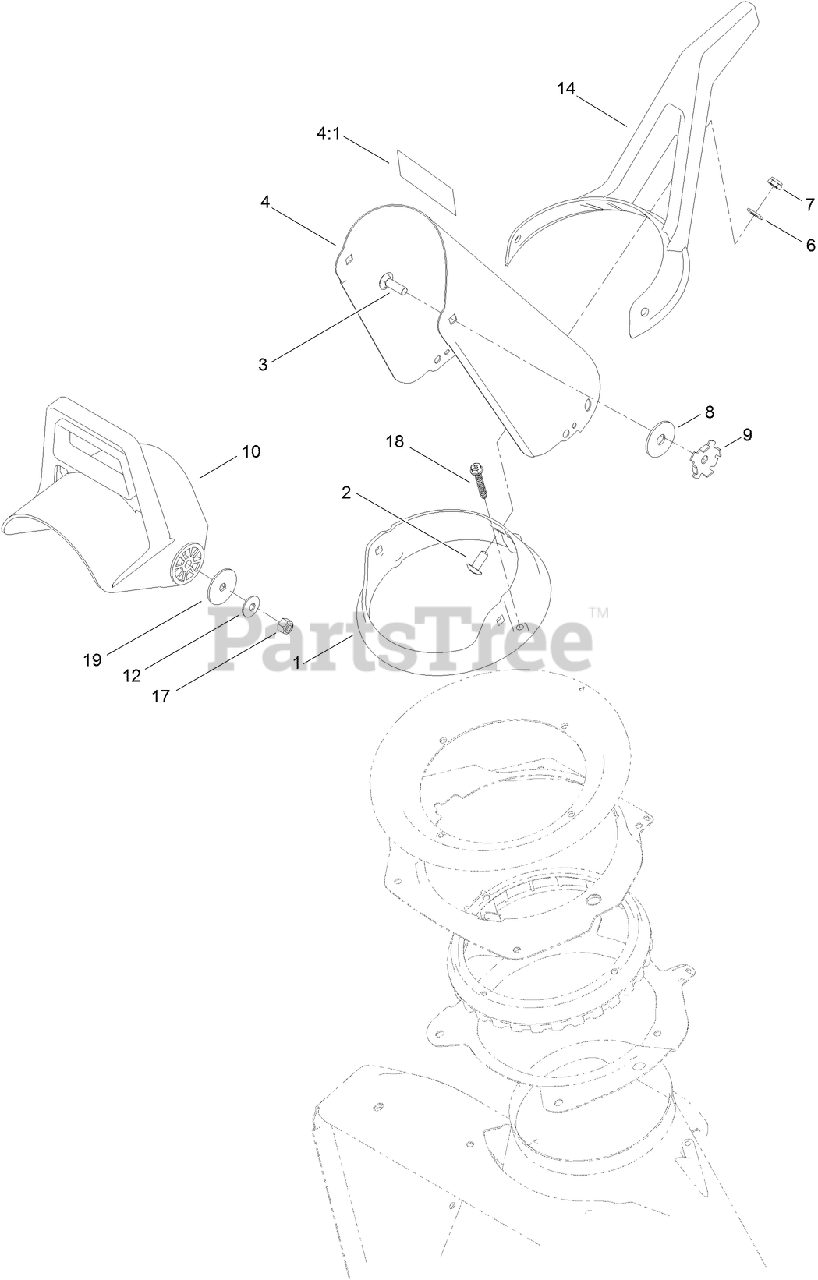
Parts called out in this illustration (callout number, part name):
1	RING-CHUTE
2	SCREW-PTH
3	SCREW-CARR
4	DISCHARGE CHUTE ASM
4:1	DECAL-DANGER, CE
6	WASHER-FLAT
7	NUT-LOCK, NI
8	WASHER-RUBBER
9	PLATE-FRICTION
10	CHUTE-DEFLECTOR
12	WASHER-BELLEVILLE
14	HANDLE-CONTROL, CHUTE
17	NUT-LOCK, NI
18	SCREW-PLASTITE
19	WASHER-FLAT
